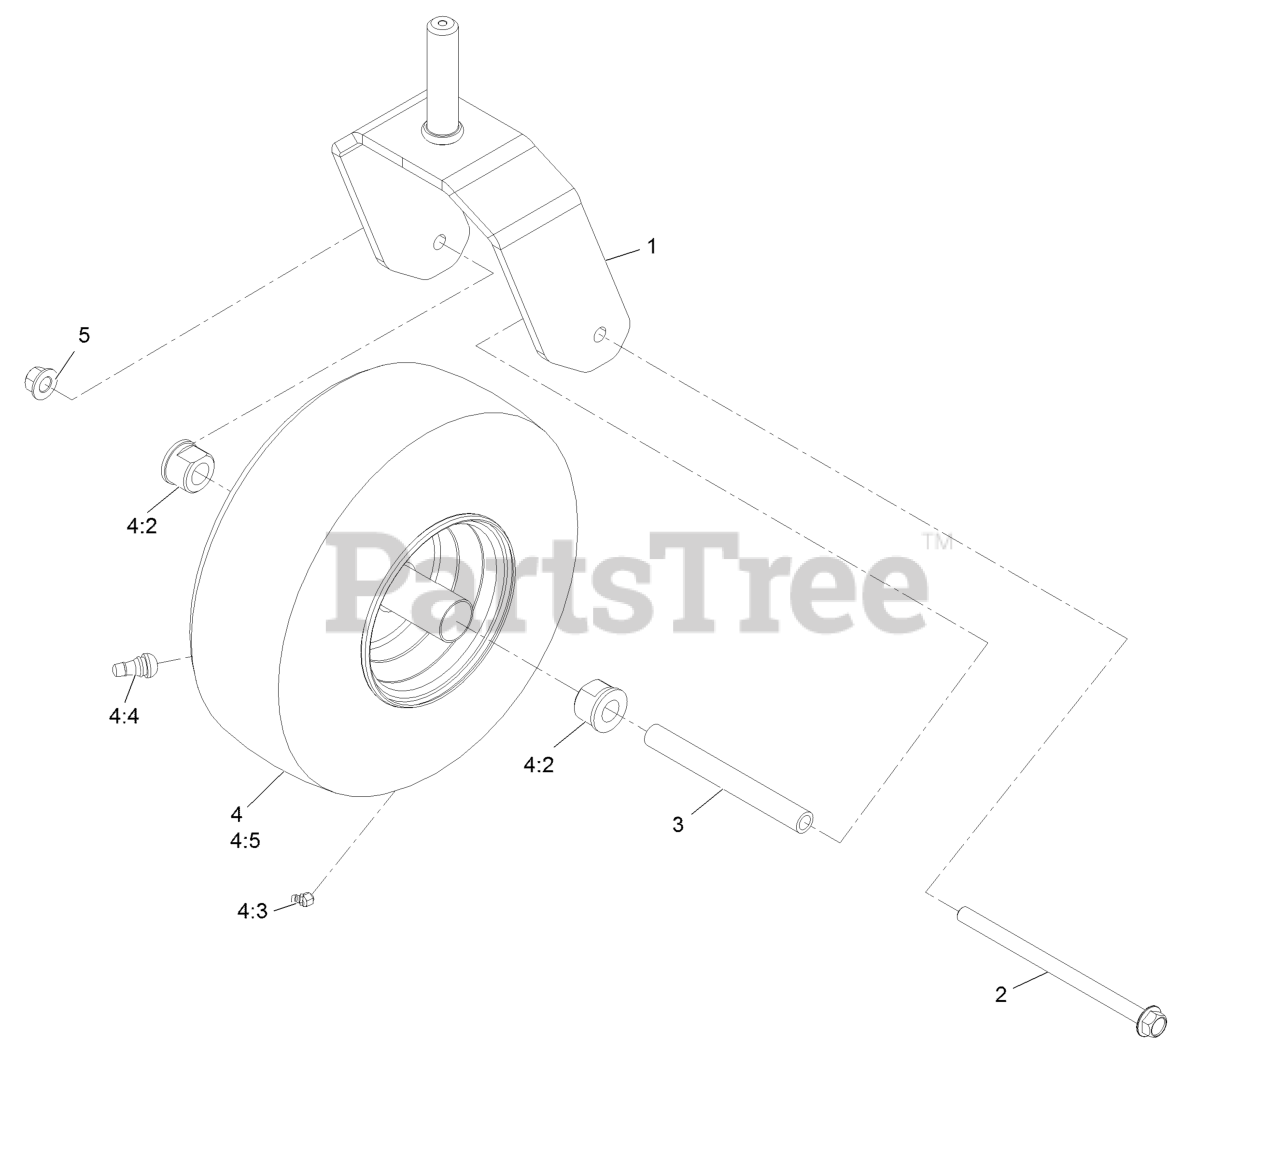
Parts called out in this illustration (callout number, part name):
1	Fork-Caster
2	Screw-HHF
3	Spanner-Wheel, Caster
4	ASM, Tire & Wheel
4:2	Bushing-Flange
4:3	Fitting-Zerk
4:4	Valve
5	Nut-Lock 1/2-13
